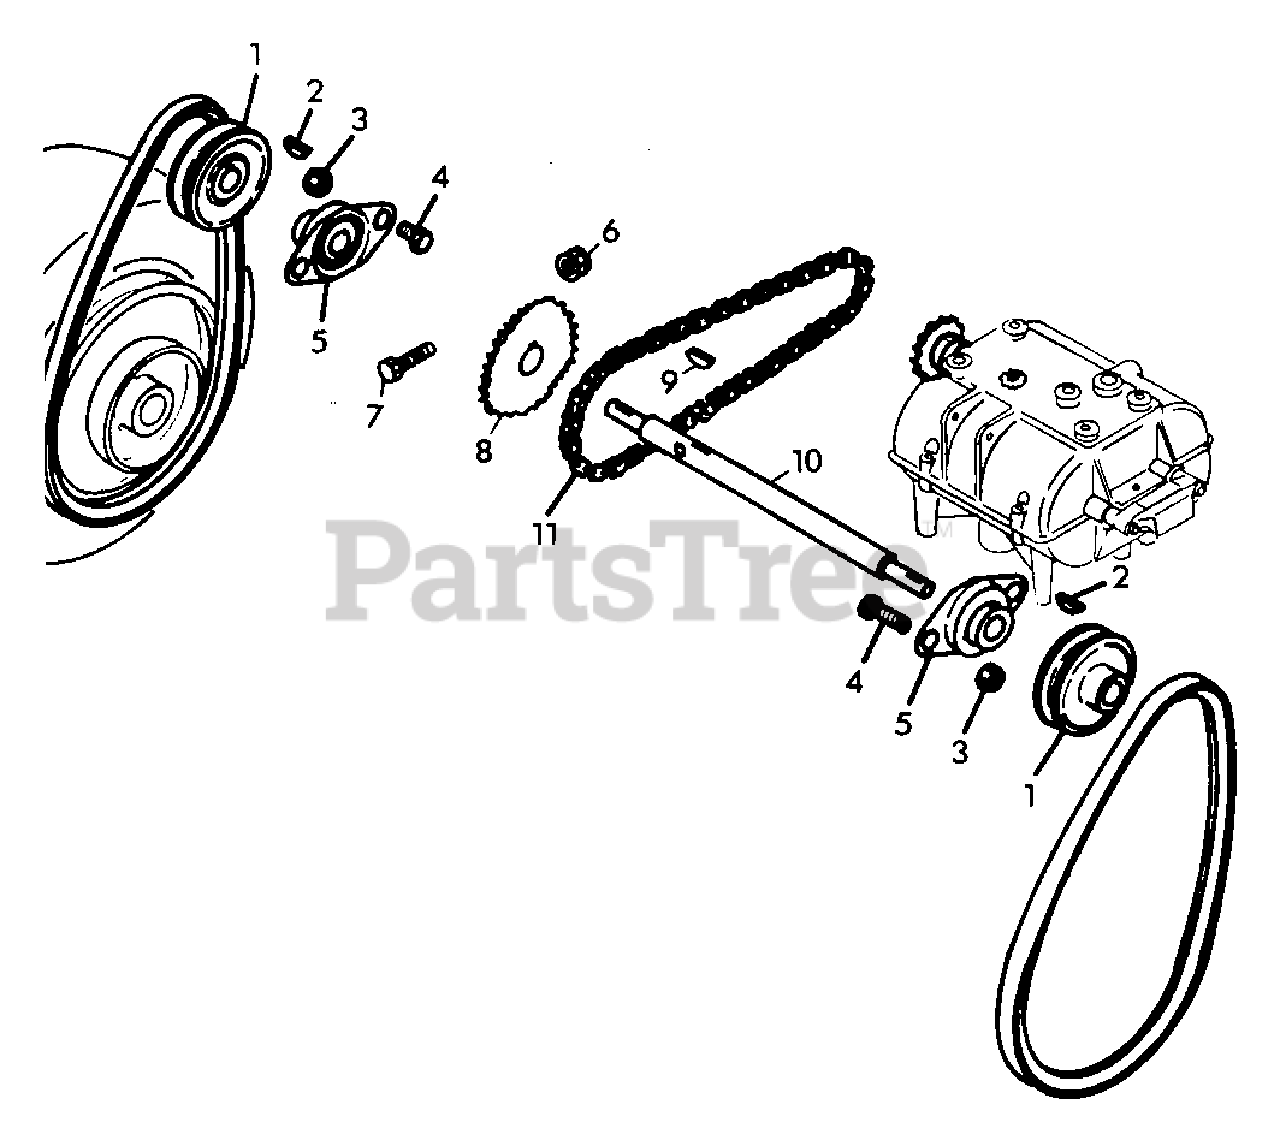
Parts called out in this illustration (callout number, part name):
1	Pulley, Jack-Shaft
2	Key, Woodruff 3/16x.750 Hard
3	Nut, Look 3/8-16
4	Bolt, Hex 3/8-16x.75
5	Bearing, Fan
6	Nut, Lock 1/4-20
7	Bolt, Hex 1/4-20x2.25
8	Sprocket, 28T .5 Pitch
9	Key, Woodruff .25x.75 Hard
10	Shaft, Jack
11	Chain, No. 40
